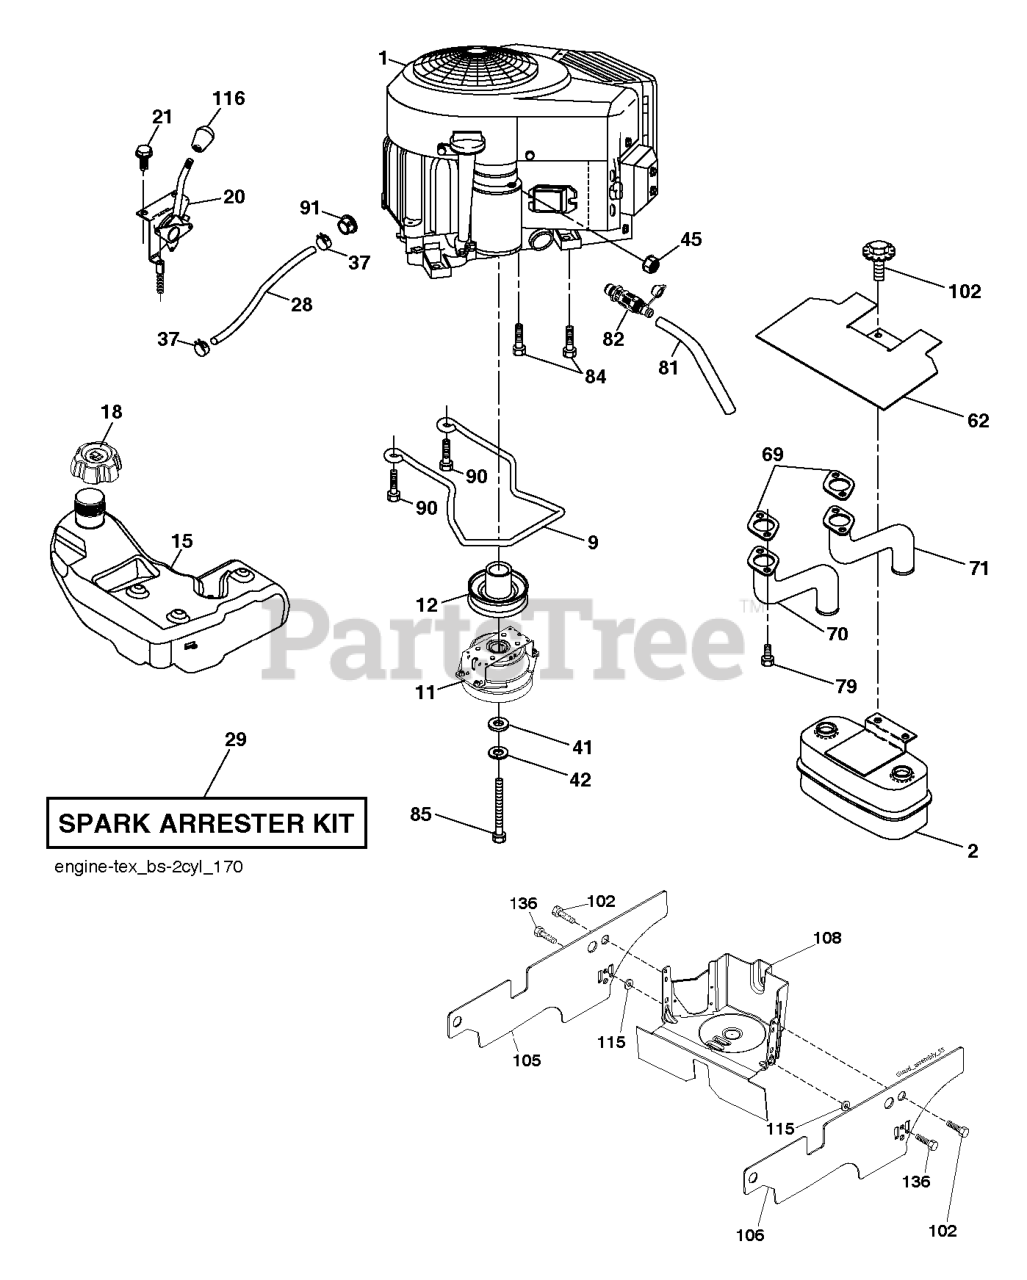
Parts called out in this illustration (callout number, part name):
2	MUFFLER.ASM.TWIN.MNTG.BRACKET
11	CLUTCH.OGURA.5.0PD.GT1.5A-EH07
12	PULLEY.ENGINE.TUFFTORQ
15	Tanks
18	CAP ASSY FUEL 3" GRAY
18	FUEL CAP
20	THROTTLE.PRO.RSTART. 38
28	LINE.FUEL.64"REAR.EMIS
29	KIT.SPARK ARRESTOR 794945 B&S
37	HOSE CLAMP
62	SHIELD.HEAT.MUFFLER
69	GASKET.MUFFLER
70	EXHAUST.TUBE.LH.BS/TWIN
71	EXHAUST.TUBE.RH.B&S.TWIN.INTEK
81	TUBE, DRAIN OIL ASM.
82	VALUE.OIL.DRAIN
84	SCREW.3/8-16
85	BOLT.HEX.7/16-20X3.75.GR5.RED
90	SCREW 3/8-16X1
91	BUSHING.1.375OD
102	SCREW
105	SHIELD.SIDE.LH.46"FRN.TEX.BLK
106	SHIELD.SIDE.RH.46"FRN.TEX.BLK
108	COVER.PULLEY.ENG.W/SHLD.38"42"
116	KNOB - SHIFT
